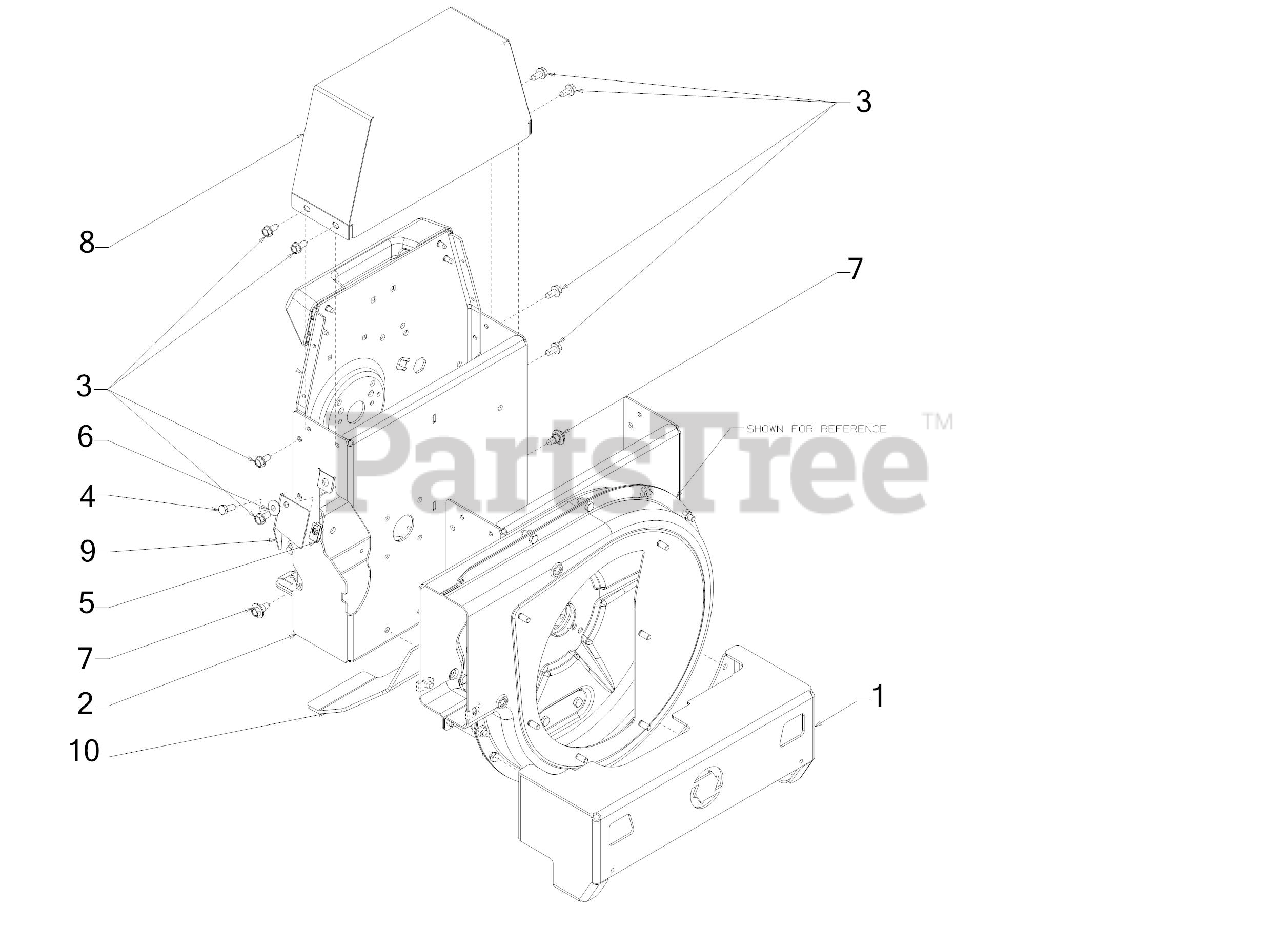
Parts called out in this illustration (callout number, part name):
1	WHEEL FRAME WELDMENT
2	FRAME WELDMENT ASSEMBLY
3	SCREW 5/16-18 x .750
4	SCREW 5/16-18 x .75 GR5
5	U-NUT
6	BELL WASHER .337 X.867 x .057
7	SHOULDER SCREW .43X.29X5/16-18 TT
8	FRAME MOUNTING COVER BRACKET
9	PULL COVER BRACKET
10	SPACER BRACKET
